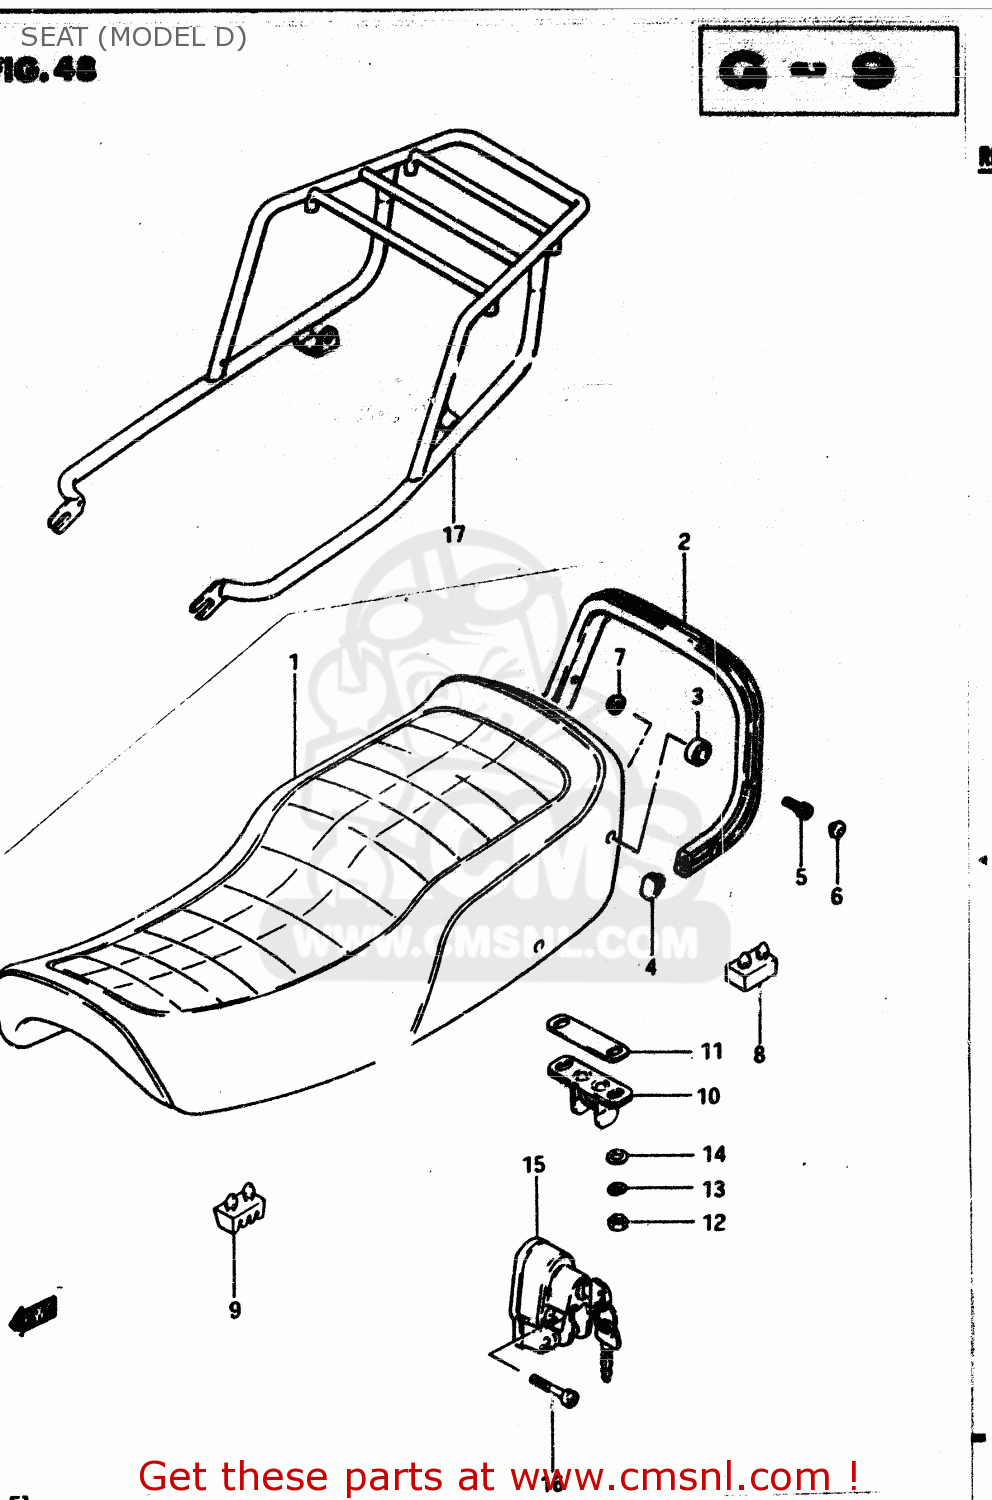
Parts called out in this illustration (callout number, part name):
1	SEAT (BLACK)
2	HANDLE,PILLION RIDER
3	SPACER,REAR
4	END,PILLION RIDER HAND
5	BOLT
6	CAP(OD:14.5)
7	NUT
8	CUSHION(40X23X12.7)
9	CUSHION,SUPPORT(50X25X32)
10	STRIKER,SEAT LOCK
11	SHIM,SEAT LOCK STRIKER
12	NUT 6MM
13	LOCK WASHER
14	WASHER
15	LOCK ASSY,HELMET
16	BOLT 5X25
17	CARRIER, SPORTS
